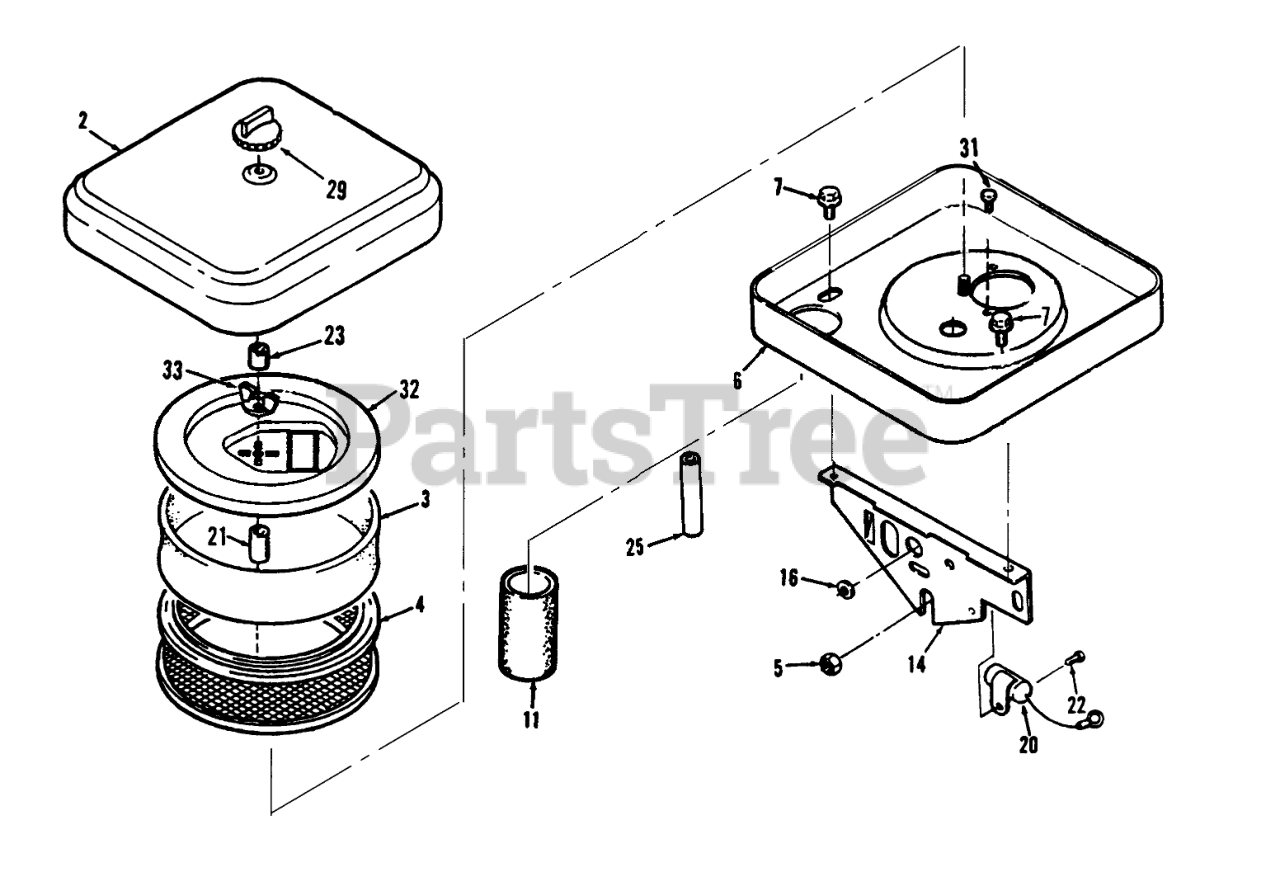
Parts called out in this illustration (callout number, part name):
2	AIR-CLEANER COVER
3	AIR CLEANER ELEMENT
4	Stationary Guard
6	AIR-CLEANER HOUSING
7	SCREW-TAPPING
11	AIR INTAKE TUBE
14	SUPPORT-AIR CLEANER
16	Grommet
20	Capacitor (300 VD)
22	SCREW #10-32 X 5/8
23	SPACER-RUBBER
25	BREATHER TUBE
29	KNOB-TOOL LESS
31	MACHINE SCREW
32	Cover-Element
33	1/4-20 WING NUT
